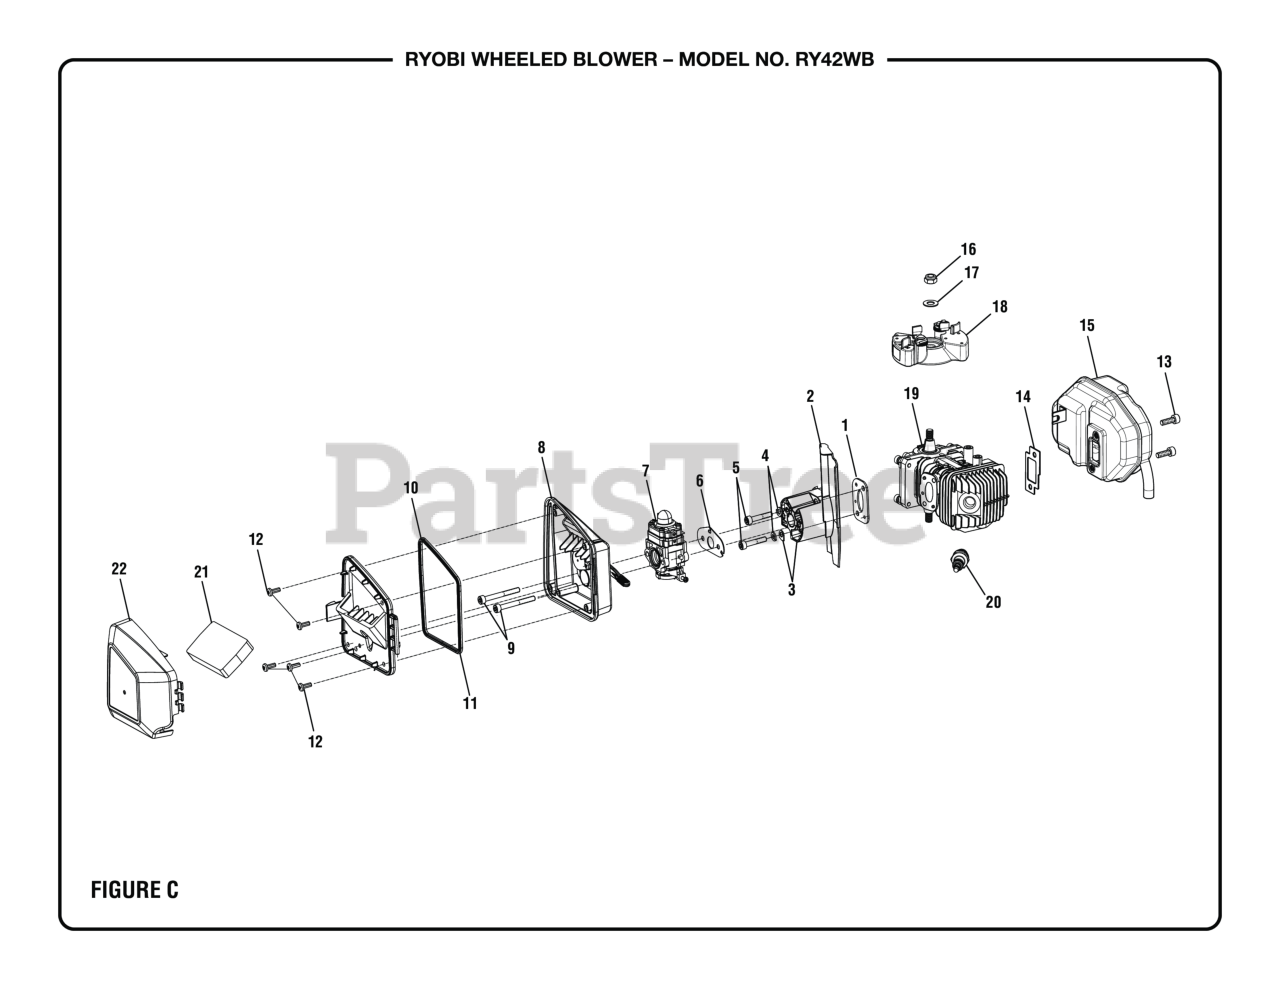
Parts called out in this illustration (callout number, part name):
1	Heat Dam Gasket
3	Washer (Heat Dam)
4	Spring Washer (M5)
5	Screw (M5 x 0.8 in.)
6	Gasket Carb-Heat Dam
7	Carburetor (Walbro, WYJ-536)
8	Air Box Base
9	Cap Screw (M5 x 45 mm, T25 Torx Soc. Hd.)
10	Airbox Gasket
12	Screw (M4 x 12 mm, Slotted Recessed Pan Hd.)
13	Screw (1/4-20 x 5/8 in.)
15	Exhaust Assembly
16	Lock Nut (M8)
17	Washer (ID9 x OD17.7 x 1.1t)
18	Flywheel Assembly
19	Short Block Assembly
20	SPARK PLUG (CHAMPION RCJ4)
21	Air Filter
22	Air Box Cover
